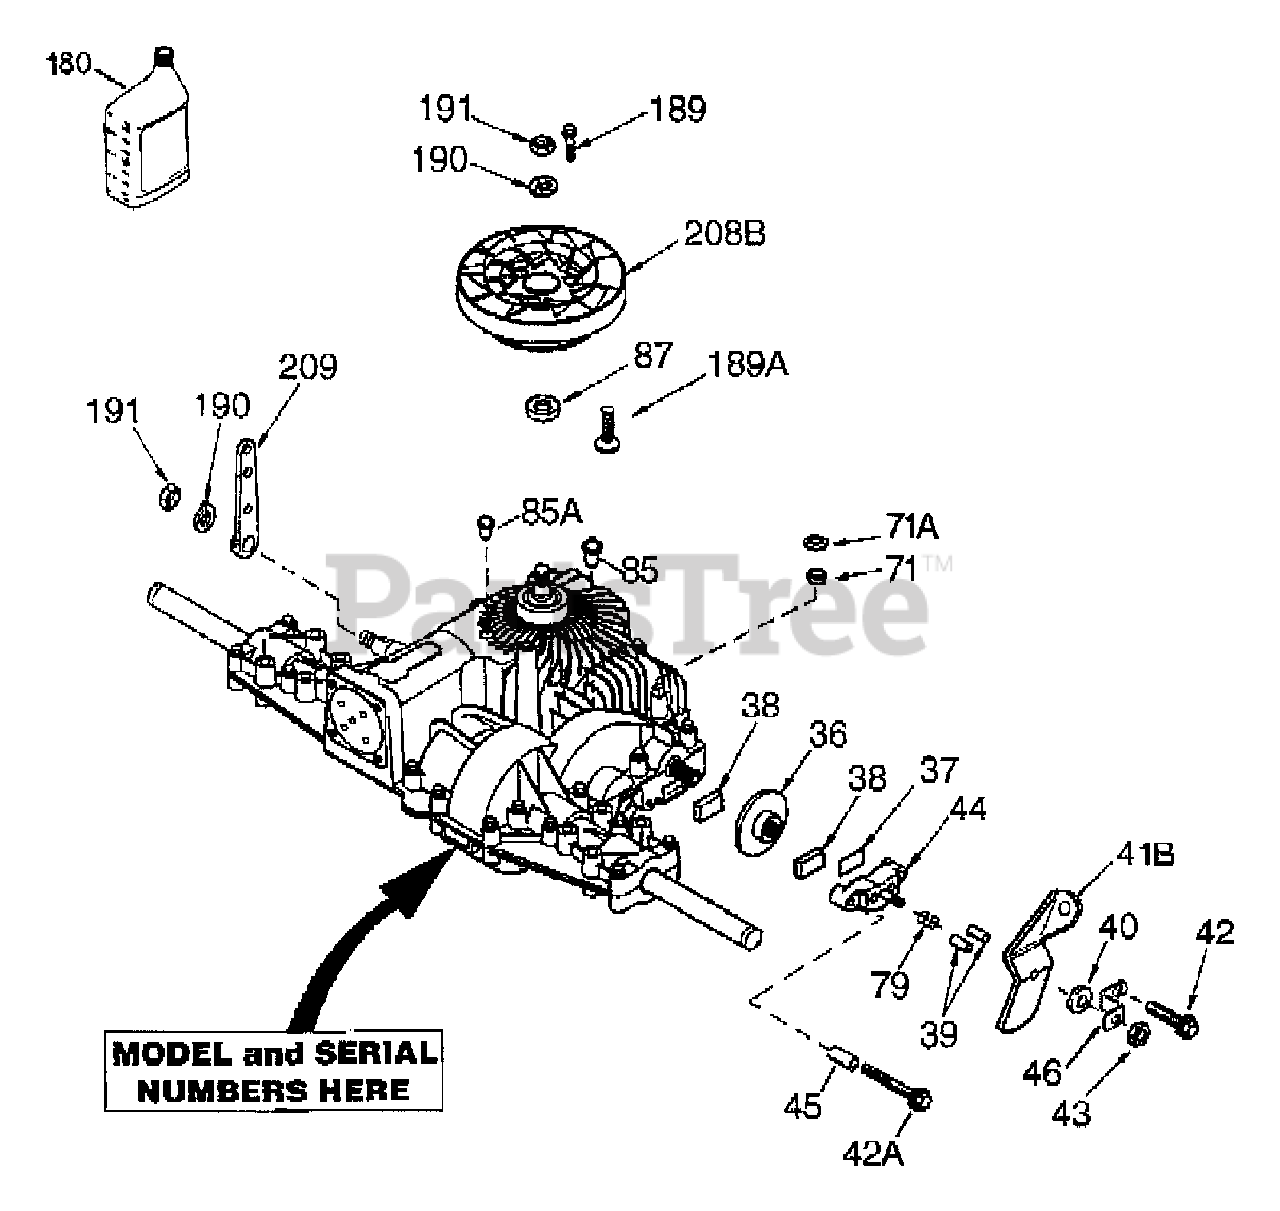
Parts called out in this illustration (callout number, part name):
36	Brake Disc
37	Brake Pad Plate
38	Brake Pad
39	Dowel Pin
40	Flat Washer
41	Brake Lever
42	Screw, 1/4-20 x 1-1/4"
42A	Screw, 1/4-20 x 2-1/4"
43	Locknut, 5/16-24
44	Brake Pad Holder
46	Brake Lever Bracket
71	Square Cut Ring
71A	Pushnut, 9/16"
87	Oil Seal, 5/8"
180	Gear Oil 80W90
189	Drive Screw #6 x 1/2"
189A	Screw, 10-32 x 1/2"
190	Lockwasher
191	Nut, 7/16-20
208B	Fan/Coupling
209	Control Lever
